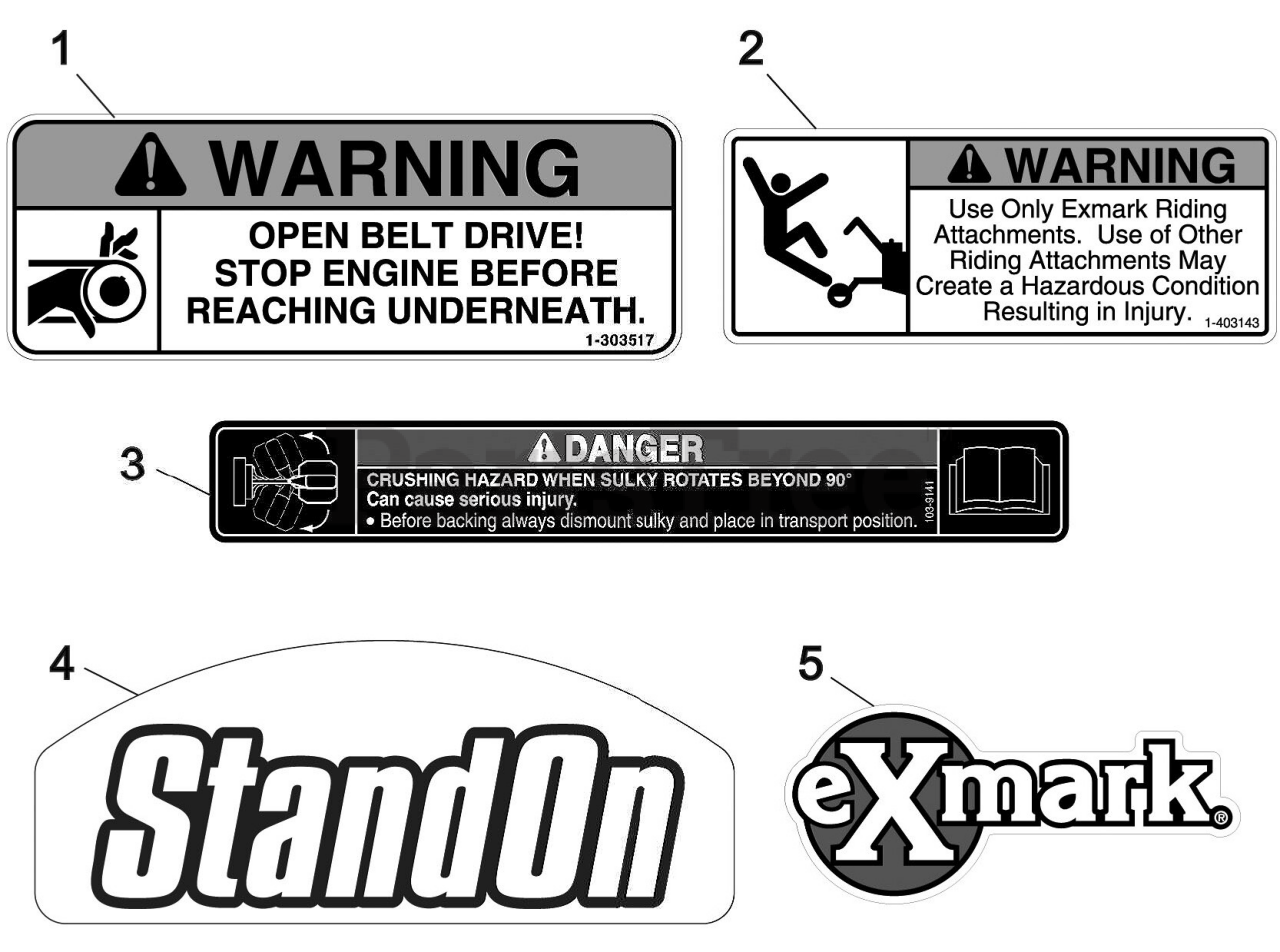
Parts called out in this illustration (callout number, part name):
1	DECAL,BELT DRIVE
2	DECAL,SULKY WARNING
3	DECAL,SULKY
4	DECAL,STANDON
5	DECAL,EXMARK
